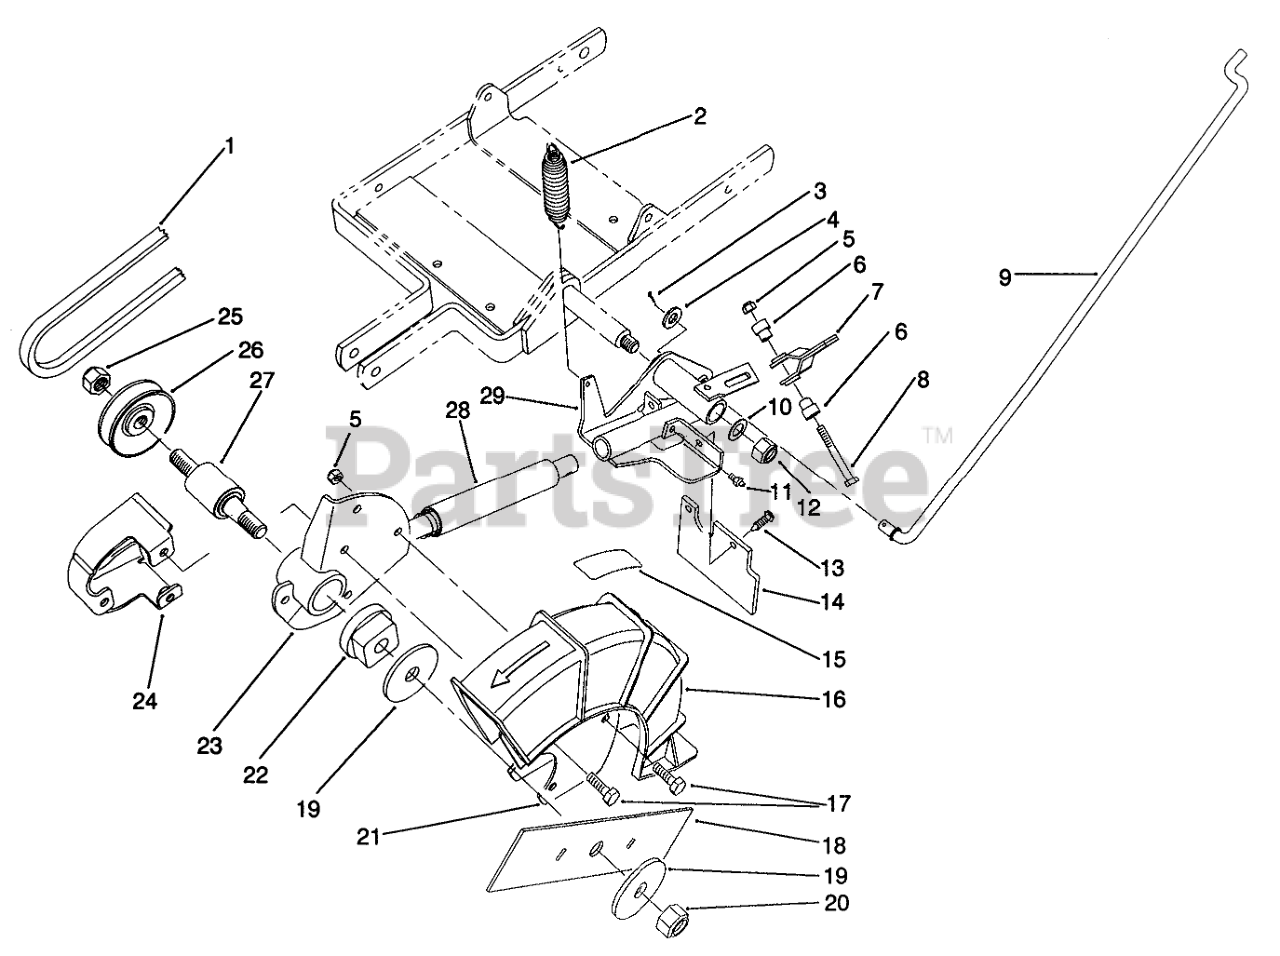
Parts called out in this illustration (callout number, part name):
1	V-BELT
2	EXT. SPRING
3	PIN-COTTER
4	WASHER-FLAT
5	NUT-LOCK, NI
6	SPACER-PIVOT LEVER
7	LEVER WA
8	SCREW-HH
9	LOWER CONTROL ROD
10	WASHER-PLAIN
11	FITTING-GREASE
12	NUT-LOCK, NI
13	PANEL FASTENER
14	RUBBER GUARD
15	DECAL-BLADE
16	Blade Guard Assy. (Incl. Ref. #15)
17	SCREW-HWHTF
18	9" EDGER BLADE
19	WASHER-LARGE
20	NUT-HEX
21	GUARD PLATE
22	BRG SHIELD
23	HUB ASM
24	PULLEY GUARD WA
25	NUT-LOCK, NI
26	PULLEY
27	SPINDLE ASM
28	SPRING & BELLOW ASM
29	PIVOT ARM WA
